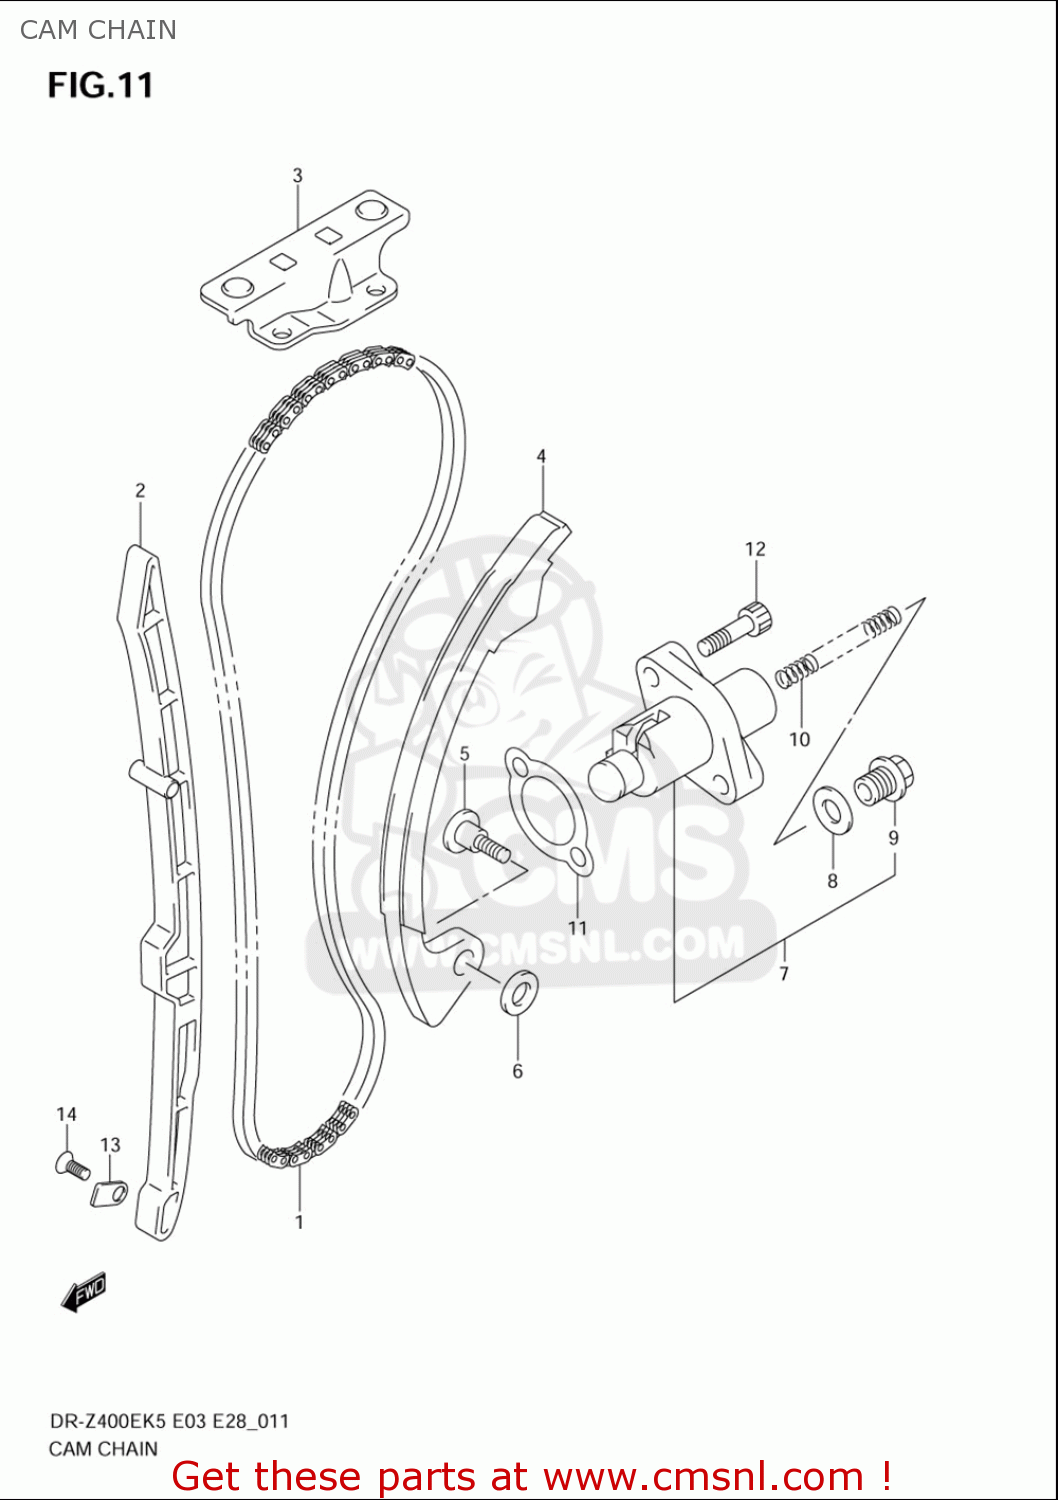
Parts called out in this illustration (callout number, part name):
1	CHAIN,CAMSHAFT DRIVE
2	GUIDE,CAM CHAIN NO.1
3	GUIDE,CAM CHAIN NO.2
4	TENSIONER,CAM CHAIN
5	BOLT,CAM CHAIN TENSIONER
6	WASHER
7	ADJUSTER ASSY,TENSIONER
8	GASKET,TENSIONER ADJUSTER (NAS)
9	PLUG,FR TENSIONER ADJ
10	SPRING
11	GASKET,TENSIONER ADJUSTER (NAS)
12	BOLT,CL.COVER
13	RETAINER,CAM CHAIN GUIDE NO.1
14	SCREW(6X12)
